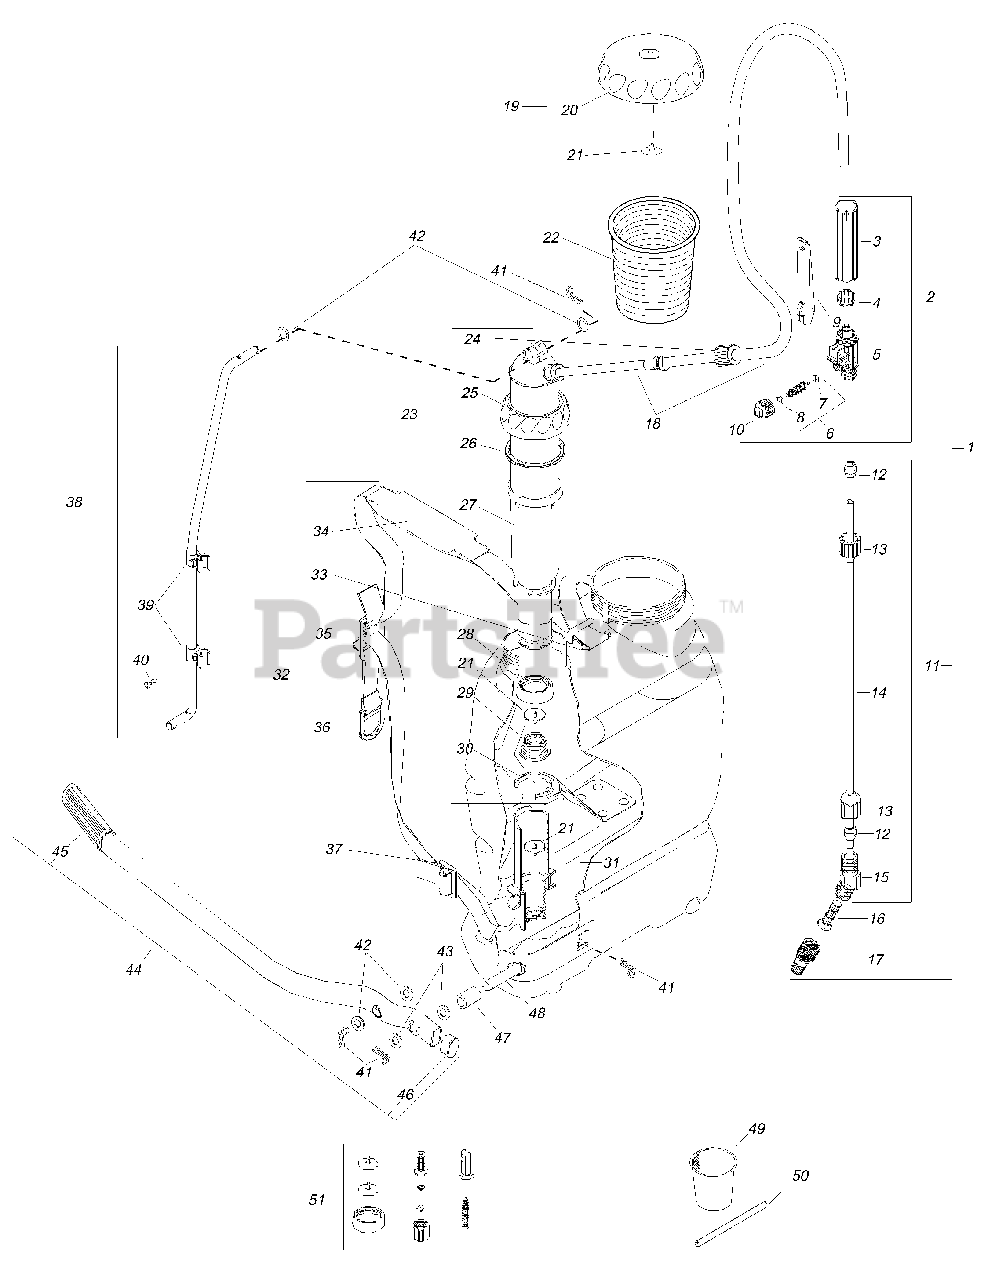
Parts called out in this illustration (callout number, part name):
1	SPRAY WAND ASSY
2	TRIGGER VALVE ASSY
3	HANDLE, TRIGGER VALVE
5	BODY, TRIGGER VALVE
6	TRIGGER VALVE NEEDLE ASSY
7	SEAL - LOWER
8	SEAL - UPPER
9	TRIGGER
10	TRIGGER VALVE CAP ASSY
11	SPRAY TUBE ASSY
12	CONE PACKING
13	SCREW
14	SPRAY WAND TUBE
15	ELBOW
16	FILTER, NOZZLE
17	ADJUSTABLE CONE NOZZLE
18	HOSE/DIP TUBE ASSY
19	LID ASSY
21	DIAPHRAGM VALVE, VITON(R)
21	VALVE, DIAPHRAGM
22	STRAINER, DEBRIS
23	CHAMBER ASSY
24	NUT - 20X1.5
25	PACKING NUT RING
26	PACKING RING VITON(R)
27	BODY, CHAMBER
28	PISTON CUP - 45 X 12
28	PISTON CUP SANTOPRENE(R)
29	PISTON CUP FASTENER
30	AGITATOR
31	CYLINDER ASSY
32	SHOULDER STRAP ASSY
33	SHOULDER STRAP RETAINING CLIP
34	SEAL - UPPER -- 50X96X35
35	BUCKLE, STRAP
36	STRAP ASSY - LOWER
37	BUCKLE, STRAP - LOWER
38	CONNECTING ROD ASSY
39	SPRAY WAND HOLDING CLIP
40	SCREW - 3.5X16
41	RETAINING CLIP
42	WASHER
43	WASHER
44	PUMP LEVER ASSY
45	GRIP
46	PLUG
47	BUSHING
48	PUMP LEVER SHAFT
49	CALIBRATED MEASURING CUP
50	DIAPHRAGM INSTALLATION TOOL
51	REPAIR AND NOZZLE KIT
